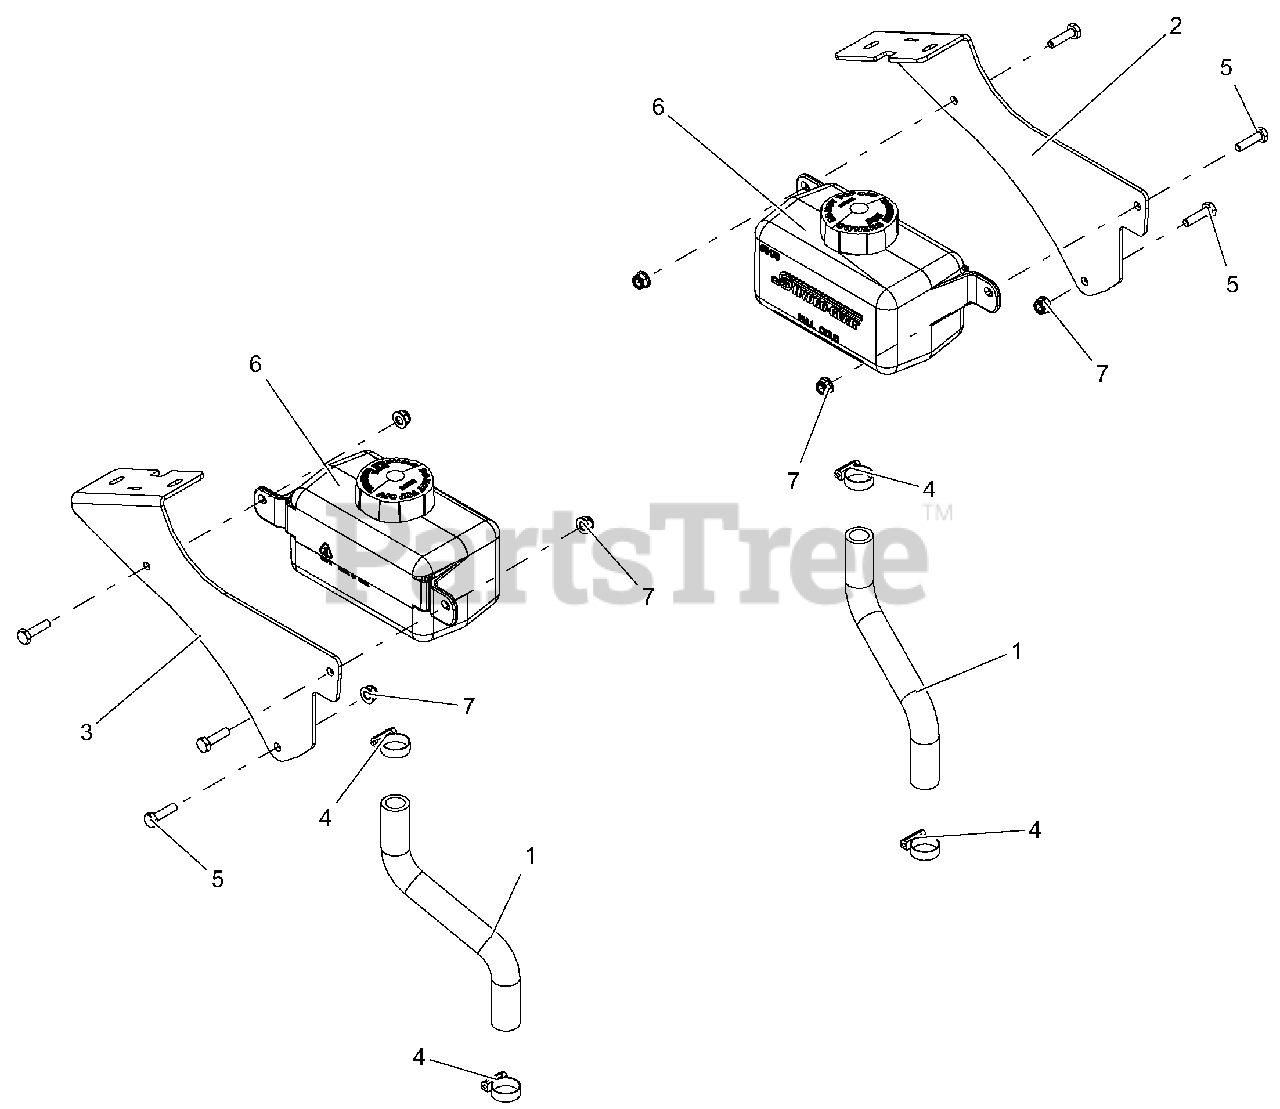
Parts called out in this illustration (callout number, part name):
1	HOSE, HYDRO OVERFLOW
2	LH HYDRO OVERFLOW TANK CARB CANISTER MTG
3	BRKT, MOUNT RH HYDRO OVERFLOW TANK CARB CANISTER MTG
4	CLAMP, .88 DIA HOSE
5	BLT-HEX .25-20X1.00 GR5 YWZC
6	TANK, HYD 1000ML
7	NUT-LK-NYL-FLG .25-20 YWZC
